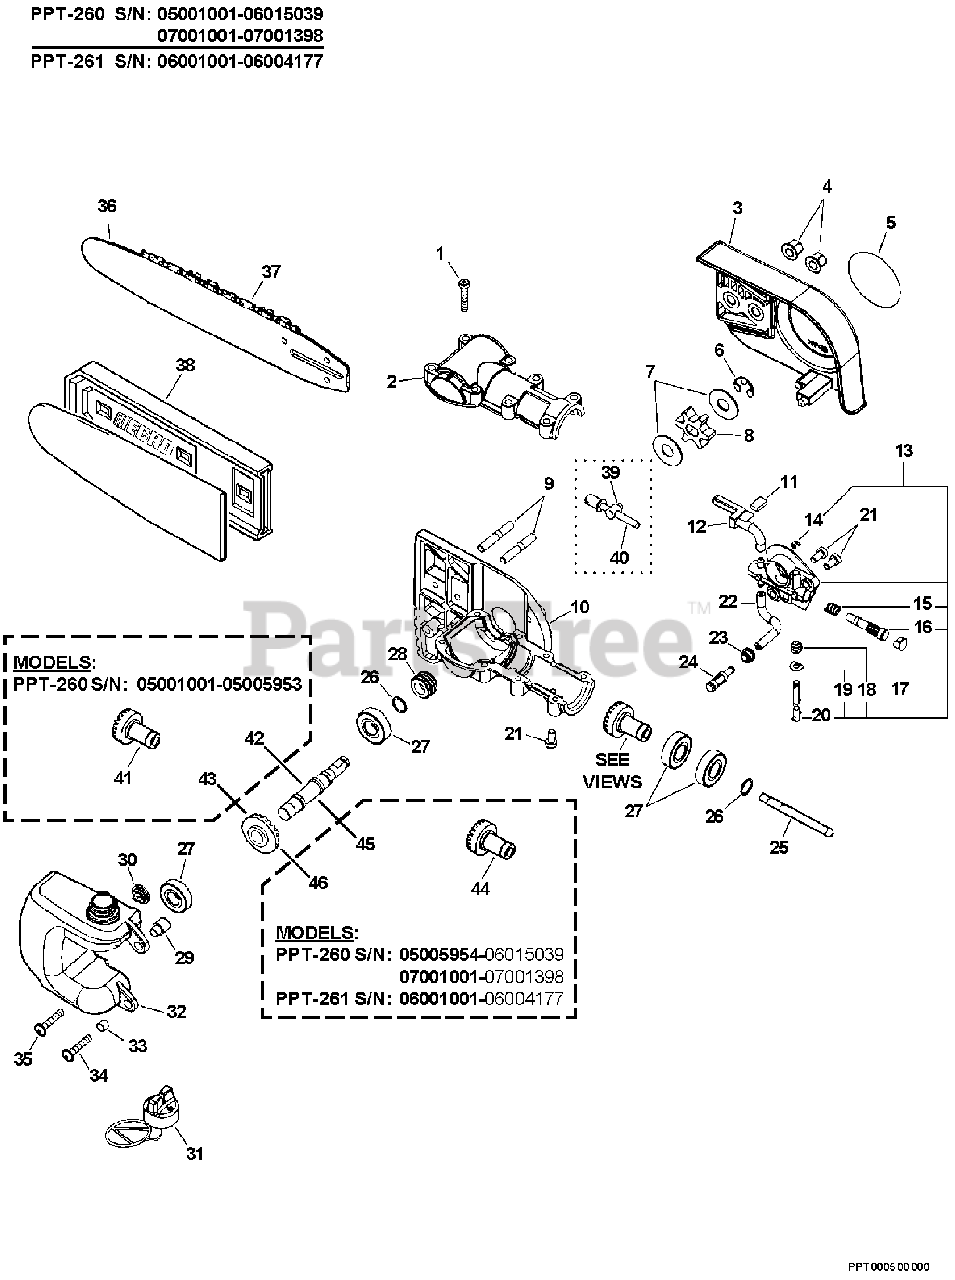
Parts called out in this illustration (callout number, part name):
1	SCREW M5×.25
2	CASE, GEAR - UPPER Ø35
3	GUARD, SPROCKET
4	NUT, FLANGE M6
5	LABEL - ECHO
6	RING, RETAINING Ø0.300
7	WASHER 10.2×24.5×1.2
8	SPROCKET, DRIVE
9	BOLT, STUD 6
10	CASE, GEAR
11	PAD, FOAM
12	PIPE, OIL OUTLET
13	AUTO-OILER ASSY
16	PLUNGER ASSY
17	CAP, OIL PUMP
20	ADJUSTER, OILER
21	SCREW M5×.8×10
22	PIPE, IMPULSE 3×6×75
23	GROMMET
24	FILTER, OIL
25	CONNECTOR, DRIVE SHAFT
26	RING, SNAP Ø12
27	BEARING, BALL
28	GEAR, WORM
29	COLLAR 6
30	VENT ASSY
31	CAP ASSY, OIL
32	TANK, OIL
33	SPACER 6.2×7.8×6
34	SCREW 5×16 MM
35	SCREW 5×28
36	GUIDE BAR - 12" -- INTENZ
37	SAWING CHAIN - 91VS - 12" -- LOW PROFILE
38	SCABBARD 12"
39	TENSIONER, CHAIN
40	BOLT 5
41	GEAR, BEVEL
42	SHAFT, GEAR
43	GEAR, BEVEL
44	GEAR, BEVEL
45	SHAFT, GEAR
46	GEAR, BEVEL
